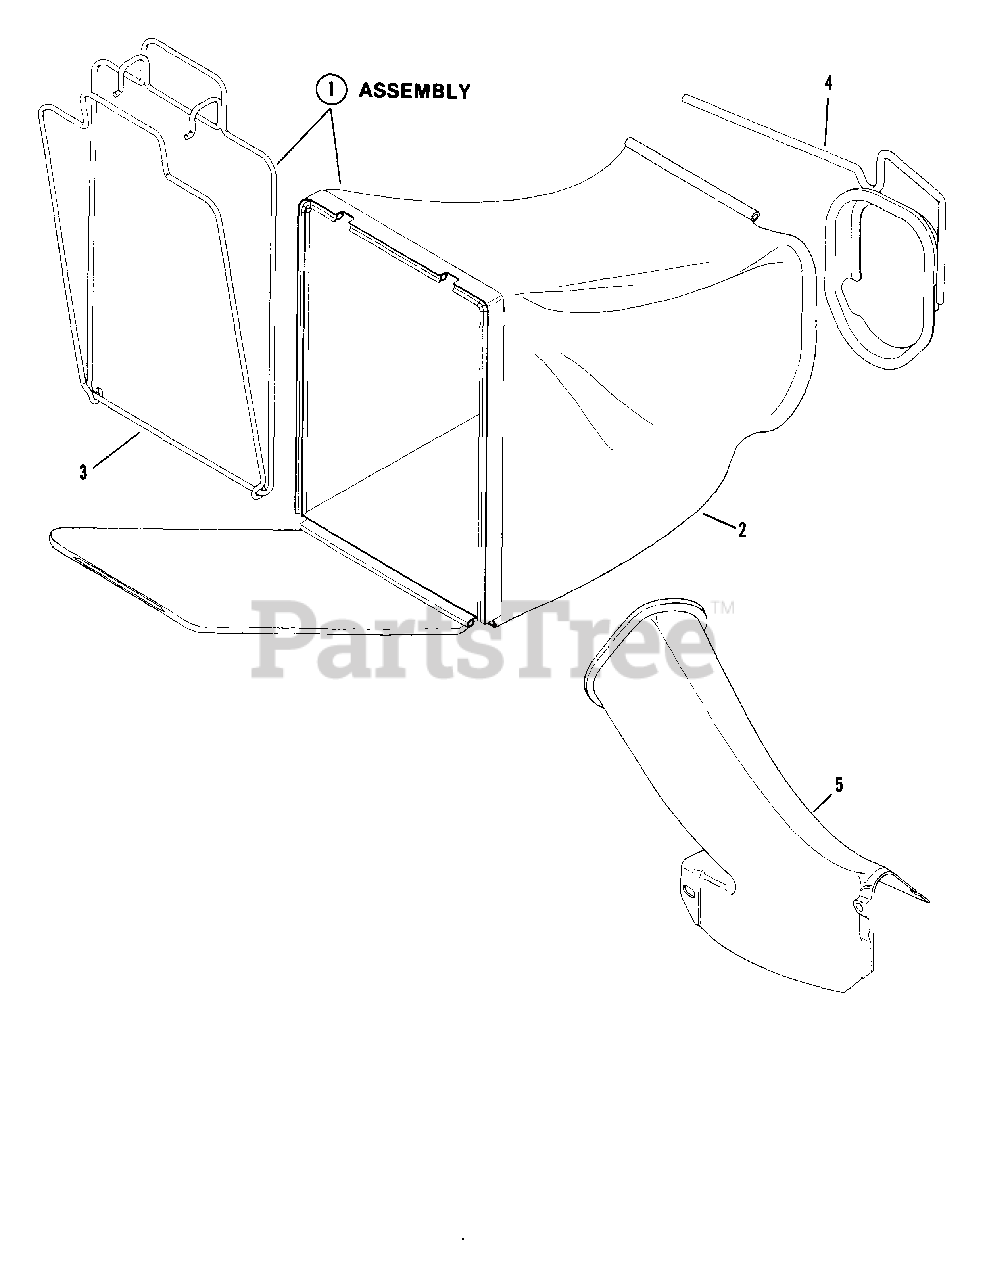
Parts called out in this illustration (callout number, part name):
1	ASSEMBLY, Grass Bag
2	BAG, Door Type (Charocoal)
3	ASSEMBLY, Bag Wire
4	CONNECTOR, Grass Bag
5	ADAPTER, Bag
